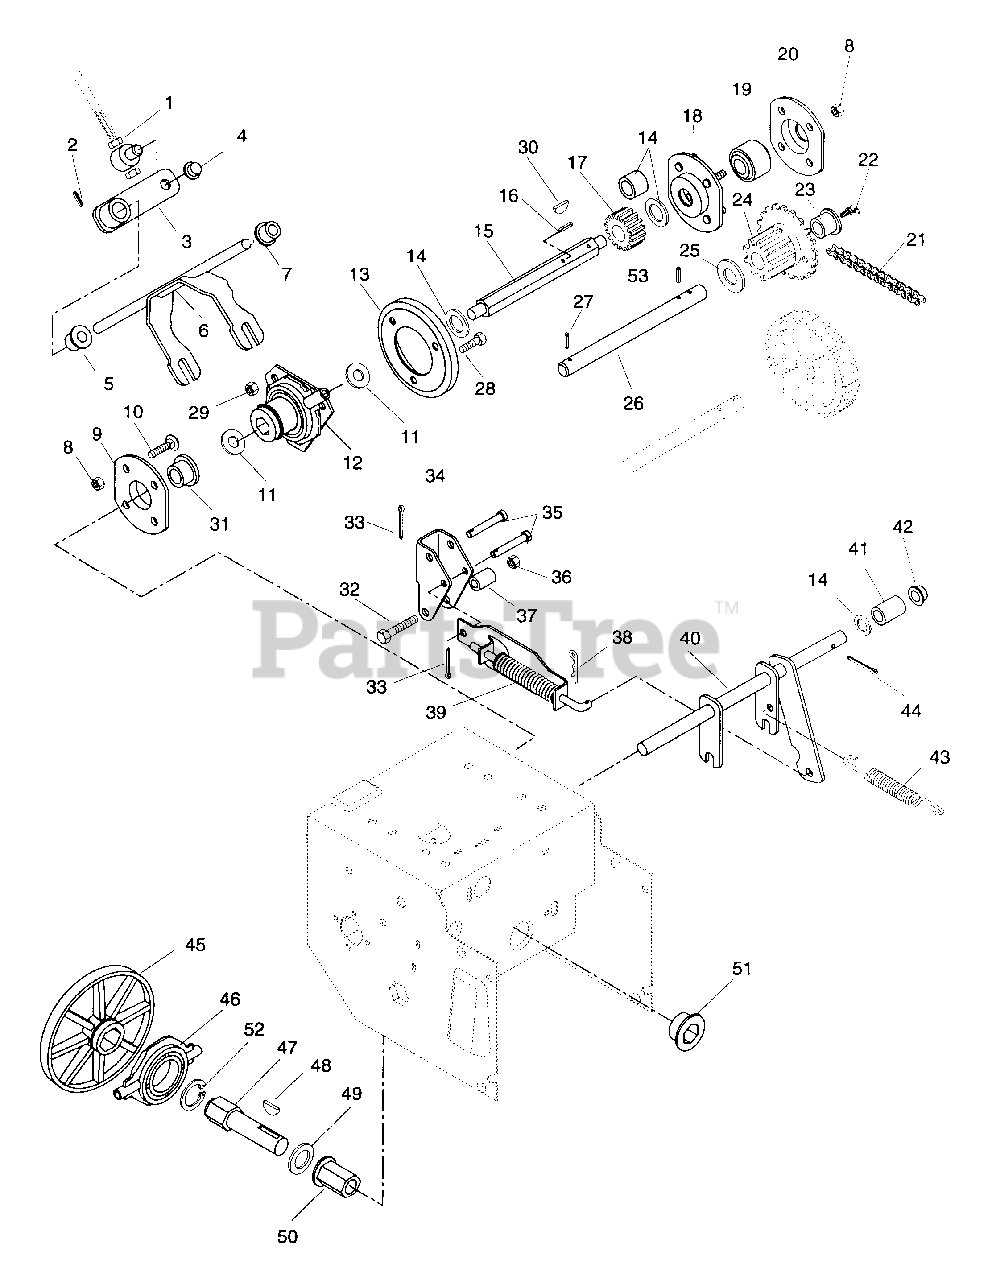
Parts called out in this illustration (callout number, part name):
2	PIN-ROLL .156X.88
3	ARM-SPEED CHANGE
4	CAP, 3/8 ROD YWZC
5	BSHG-FLG.500X.625X.312X.750NY
6	FORK-SPEED
7	BSHG-FLG .325X.444X.440X.560
8	NUT-LK DUAL FACE 10-24 PL
9	BUSHING FLANGE
10	BLT-RDHDSQNK 10-24X.38 PL
11	WSHR-FL-STL .505X1.000X.062
12	SHIFT CARRIER
13	FRICTION DISC
14	WSHR-FL-STL .531X1.062X.095 PL
14	SPACER .513X.748X.620
15	HEX SHAFT
16	PIN-ROLL .125X.88
17	PINION
17	9 TOOTH SPROCKET
18	BEARING FLANGE
19	BRG-BALL .500X1.38X.437
20	BEARING FLANGE
21	CHAIN-ROLLER #41X26 PITCHES
22	HYDRAULIC DRIVE FITTING
23	BSHG-FLG .625X.750X.500X.875BR
24	SPROCKET ASSY
25	WSHR-FL-STL .630X1.005X.062 PL
26	SHAFT-PINION
27	PIN-ROLL .125X1.00
28	BLT-HEX .25-20X.50 PL GR2
29	NUT-LK-CTR .250-20 PL
30	KEY-WDRF .125X.625X.250 SAE5
31	BSHG-FLG .500X.750X.625X.937
32	BLT-HEX .31-18X1.50 PL GR2
33	PIN COTR .09X.50 PL
34	BRACKET
35	PIN, CLEVIS .243/.248X1.50 YWZ
36	NUT-LK .312-18 GR A PL
37	SPACER -SPLIT .340X.490X1.02
38	PIN-HAIR INT .08X.18X1.18
39	TRACTION CLUTCH ASSY
40	CLUTCH FORK
41	SPACER .504X.748X.321
42	CAP, .50 ROD YWZC
43	SG-TENS .063X.44X1.56
44	PIN-COTR .12X1.0 PL
45	FRICTION PLATE
46	BEARING ASSEMBLY
47	HEX SHAFT
48	KEY-WDRF .188X.75X.313 SAE 9
49	WSHR, THRUST .625X1.125X.063
50	BSHG-FLG .625X.875X1.750X1.188
51	BSHG-FLG .875X1.25X.75X1.50HX
52	RG-RTNG-EXT 1.250X.050
53	PIN-ROLL .156X.88
